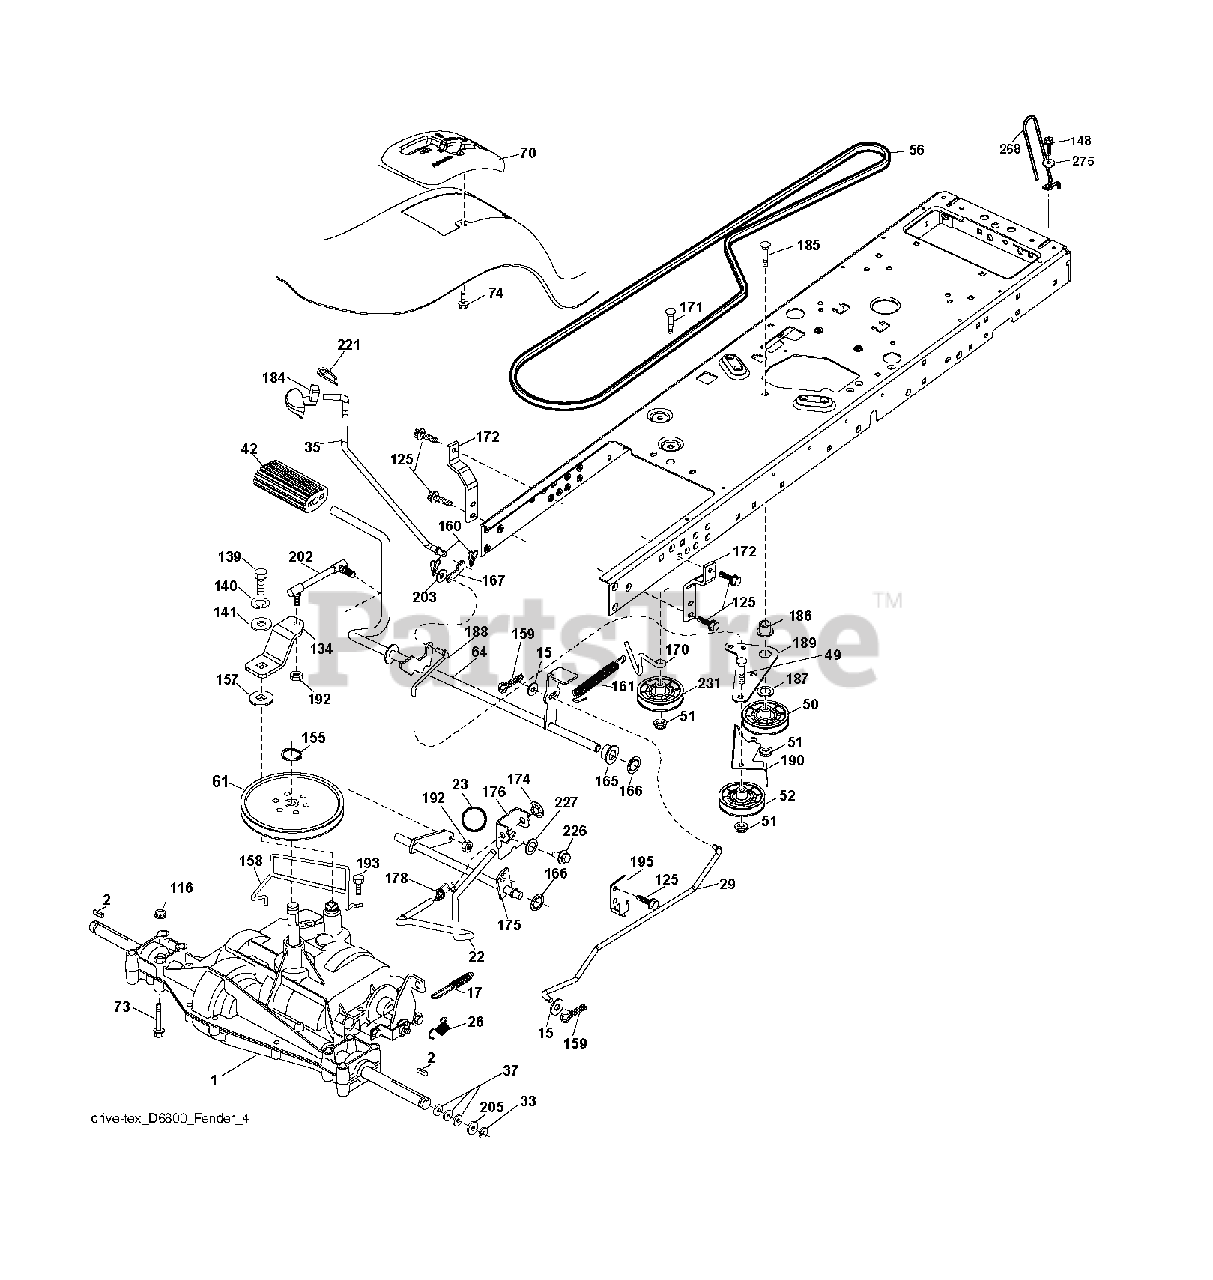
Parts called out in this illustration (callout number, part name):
2	SQUARE KEY
17	SPRING.BRAKE.PEERLESS.TEX
22	ROD.SHIFT.FENDER.TLT.2006
23	KNOB.DUCKHEAD.1/2
26	SPRING.BRAKE.RTN.GR.DR
29	ROD.BRAKE.PEERLESS
33	E-RING LT
35	ROD.BRAKE.PARKING.LT.T
42	PEDAL COVER T
49	BOLT
50	IDLER.FLAT.910.OFFSET
51	NUT LOCK FLG 3/8-16 UNC
52	IDLER.V-GROOVE.910.OFFSET
61	PULLEY TRANS
64	SHAFT.ASM.PEDAL.BRAKE.
70	CONSOLE.SHIFT.
73	BOLT HEX 5/16-18 GR 5
74	SCREW.HI-LO.CONSOLE
116	NUT LOCK HEX FLANGE 5/16-18
125	SCREW
134	ARM.SHIFT.
139	BOLT 1/4-28X3/4
140	LOCKWASHER
141	WASHER LT
148	SCREW, 3/8-16X3/4
155	RETAINING RING LT
157	WASH-SHFT PLT LT
158	KEEPER.PMS.18/20.D4365
159	COTTER PIN
160	RETAINER CLIP
161	SPRING, RETURN LT
165	BUSHING.SHAFT.BRAKE.HAND
166	NUT.PUSH.625.2006
167	LATCH.BRAKE.SPRING
170	KEEPER.V-IDLER.CENTER.
172	STRAP.TRQ.LH.GEAR.DRIV
174	NUT.PUSH.500.2006
175	SHAFT.ASM.SHIFT.
176	ARM.CLEVIS.ROD.SHIFT
178	SPRING.SHIFT.GT2006
184	HANDLE.PAKRING.BRAKE.
186	SPACER.RETAINER
187	WASHER 12/32X2X10GA
188	LINK.CLUTCH.GROUND.DRIVE
189	BELLCRANK.GROUND.DRIVE.TEX.
190	KEEPER.BELLCRANK.DRIVE
192	NUT LOCK CENTER 1/4 -28 FNTHD
193	SCREW 5/16"
195	BRKT.ROD.BRAKE.PEERLES
202	LINK.TRANSAXLE.
203	WASHER
221	RETAINER.SPRING.CLIP.H
226	BOLT FIN HEX 7/16-14 X 1
227	WASHER SERRATED
231	IDLER.V-GROOVE.1.688.OFFSET
268	WASHER
